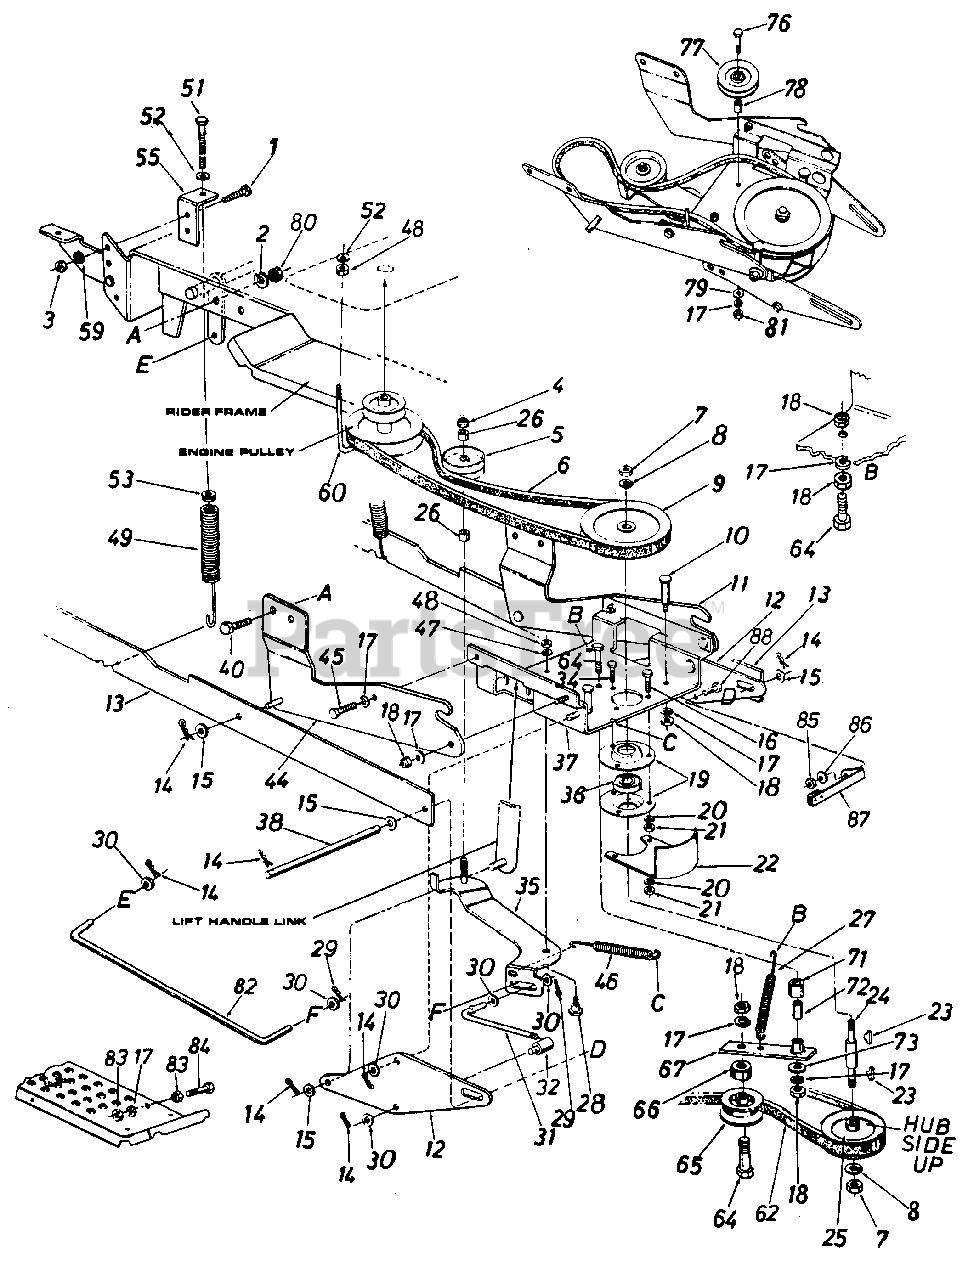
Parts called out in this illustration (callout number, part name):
1	Hex Bolt 1/4-28 x 1.0" Lg.- Grade 5
2	L-Wash. 1/4" I.D.
3	Hex Nut 1/4-28 Thd.
4	Hex Cent. L-Nut 3/8-16 Thd.
5	Idler Pulley
6	"V"-Belt
7	Hex Jam Nut 5/8-11 Thd.
8	L-Wash. 5/8" I.D.
9	5/8 Pulley x 6.5" O.D.
10	Shoulder Bolt
11	Channel Support Brkt.-R.H.
12	Linkage Brkt.
13	Linkage Arm Ass'y.
14	Intern. Cotter Pin .50" Dia.
15	Fl-Wash.
16	Hex Bolt 5/16-18 x 1.25" Lg.
17	L-Wash. 3/8" I.D.
18	Hex Jam Nut 3/8-16 Thd.
19	Bearing Housing
20	L-Wash. 5/16" I.D.
21	Hex Nut 5/16-18 Thd.
24	Pulley Spindle
25	5/8 Pulley 6.28" I.D. x 5.56" O.D.
26	Spacer.383" I.D. x.503" O.D. x.562" Lg.
27	Extension Spring .54" O.D. x 5.25"
28	Shoulder Bolt
29	Cotter Pin 3/32" Dia.
30	Fl-Wash.
31	Control Rod
32	Ferrule
34	Hex Sems Bolt 5/16-18 x .75" Lg.
35	Clutch Idler Brkt. Ass'y.
36	Ball Bearing
37	Channel Ass'y.
38	Lift Handle Shaft
40	Hex Self-Tap Scr. 1/4-20 x .75" Lg.
44	Channel Supporting Brkt.-L.H.
45	Hex Bolt 3/8-16 x 1" Lg.
46	Extension Spring
47	L-Wash. 5/16" I.D.
48	Hex Nut 5/16-18 Thd.
49	Helper Spring
51	Hex Bolt 5/16-18 x 2.0/' Lg. Special
52	Bell-Wash. .345" I.D. x .88" O.D. x .06"
53	Spring Insert
60	J-Bolt 5/16-18 Thd.
62	"V"-Belt
64	Hex Bolt 3/8-16 x 2" Lg.
65	Idler Pulley
66	Spacer .385" I.D. x .503 O.D. x.562" Lg.
67	Idler Arm Ass'y.
71	Spacer.38n I.D.
72	Spacer .3775" I.D. x .6" O.D. x 8.3" Lg.
73	Fl-Wash. 3/8" I.D. x 1 O.D. x 1.27"
76	Hex Bolt 3/8-16 x 2.5" Lg. (Grade 5)
77	Idler Pulley .38" I.D. x 3.06" O.D.
78	Spacer .385" I.D. x .63" O.D. x.76" Lg.
79	Fl-Wash. .39" I.D. x 1-3/4" O.D. x 3/16"
80	Hex L-Nut 1/4-20 Thd.
81	Hex Nut 3/8-16 Thd.
82	Clutch Control Rod
83	Hex Nut 3/8-24 Thd.
84	Hex Bolt 3/8-24 x 2.25" L9
85	Hex Nut 3/8-16 Thd.
86	Bell-Wash. 3/8" I.D.
87	Auger Brake Brkt. Ass'y.
88	Hex Bolt 3/8-16 x 5/8n Lg.
